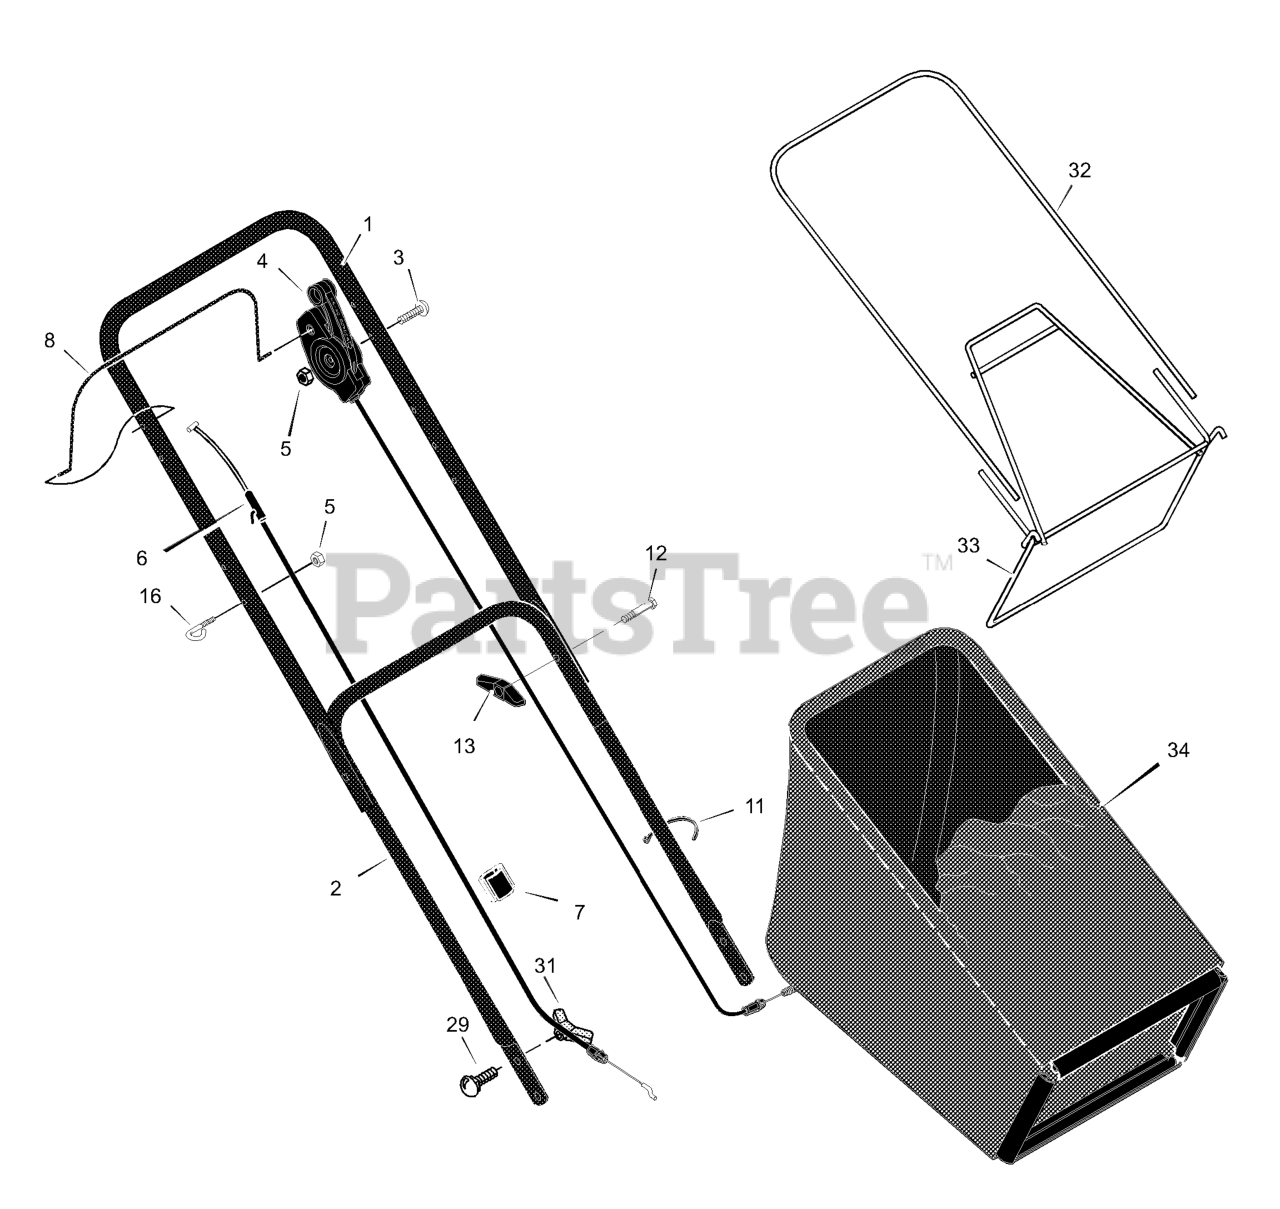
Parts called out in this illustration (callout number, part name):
1	Handle, Upper
2	Handle, Lower
4	Control, Drive
5	Locknut
6	Cable, Stop
7	Fastener, Cable
8	Lever, Stop
11	Fastener, Cable
13	Knob
16	Guide, Rope
29	Bolt, Carriage
31	Knob, Plastic
32	Tube, Bag
33	Frame Assembly
34	Bag, Cloth
